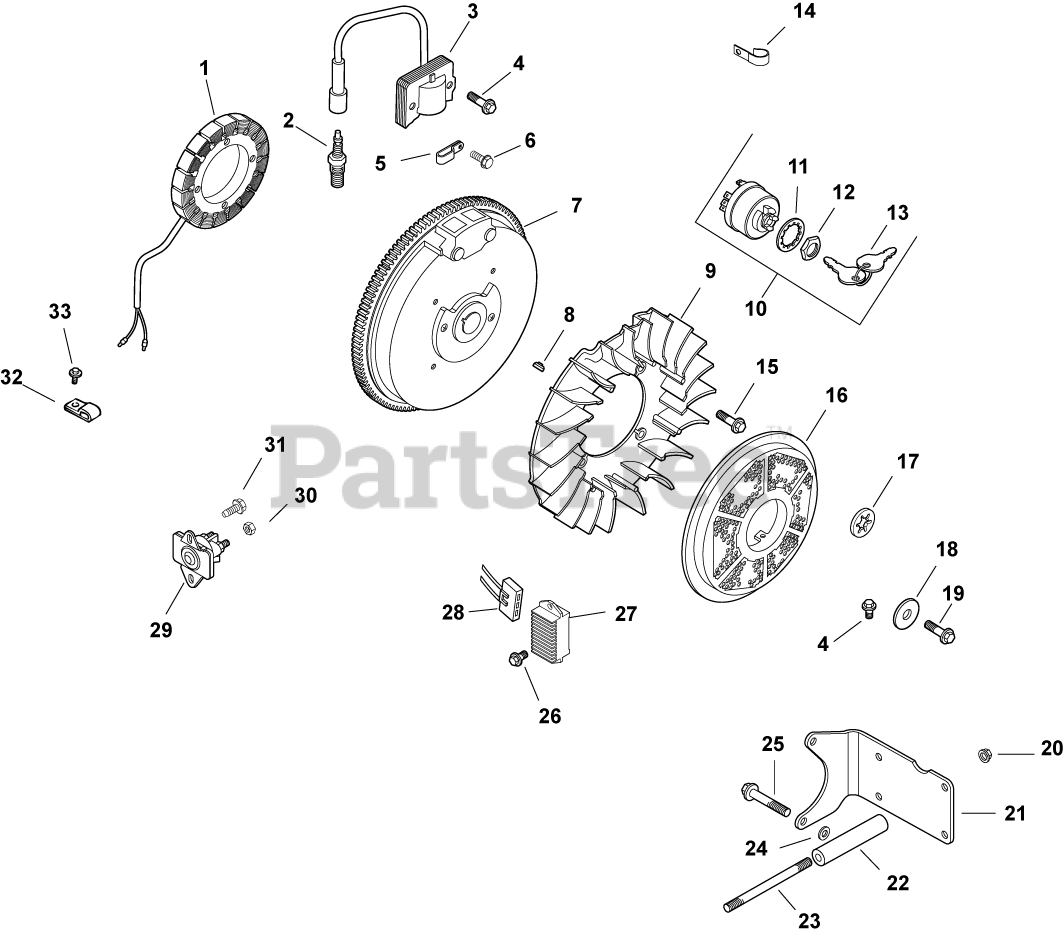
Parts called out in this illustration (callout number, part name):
1	KIT, 15 / 20 AMP STATOR
2	PLUG, SPARK (STD)
3	MODULE, IGNITION
4	SCREW, FLG THD FRM M5X.8X20-(#25086399S)
6	SCREW, FLG THD FRM M5X.8X10
8	KEY, 3/16" X 5/8"
10	SWITCH ASSY, KEY (KM)-USE 25 099 32-S
11	WASHER, INTERNAL TOOTH
12	NUT, KEY SWITCH
13	KEY, SET -USE 48 340 01-S
14	CLIP, CABLE
15	BOLT, SHOULDER
18	WASHER, FLAT 13/32"
19	SCREW, FLG M10X1.5X45 - (#25086361S)
20	NUT, FLG M8X1.25
21	BRACKET, FUEL TANK
23	STUD, M8X1.25X133-USE 25 755 54-S
24	WASHER, FLAT 11/32"
25	SCREW, FLG M8X1.25X50
26	SCREW, FLG M6X1.0X16
27	REG/RECT-15 AMP (KM)-USE 41 403 10-S
28	CONNECTOR, BODY (KM)-USE 25 155 41-S
29	SOLENOID - WATERPROOF (KM)-USE 25 435 08
30	NUT, JAM 1/4-20 GRADE 2
31	SCREW,FLG THD FRM M6X1.0X16-(#25086397S)
32	CLIP, TUBE & WIRING (KM)
33	SCREW, M5X0.8X25 - (#25086402S)
